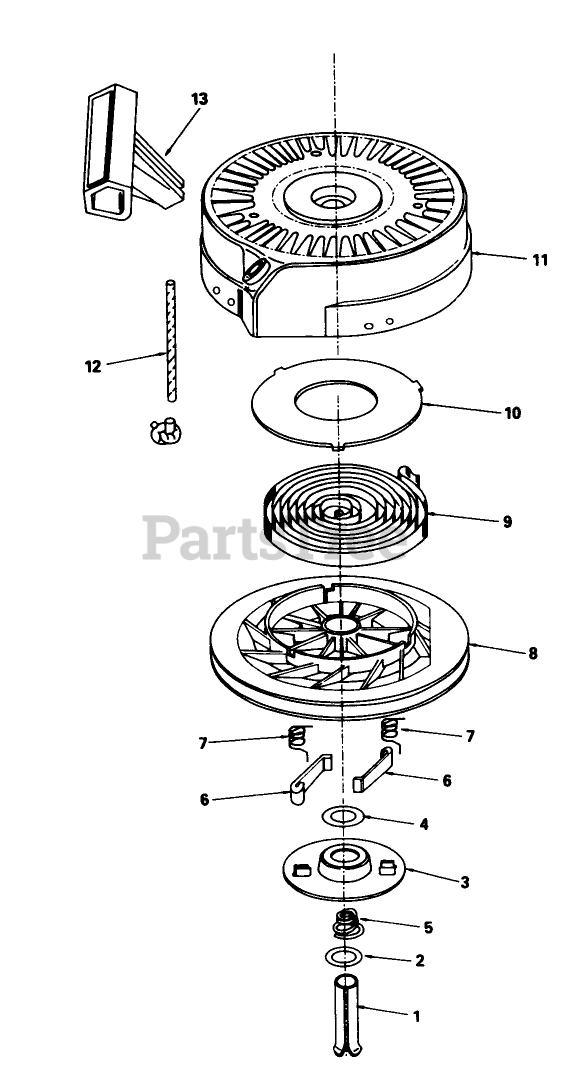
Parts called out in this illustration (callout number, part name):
1	Pin Spring
3	Retainer
5	Brake Spring
6	Dog-Starter
7	Spring-Dog
8	Pulley
9	Rewind Spring
10	Cover-Spring
11	Housing-Starter
12	Rope-Starter (98 cut to length)
13	Handle-Starter
